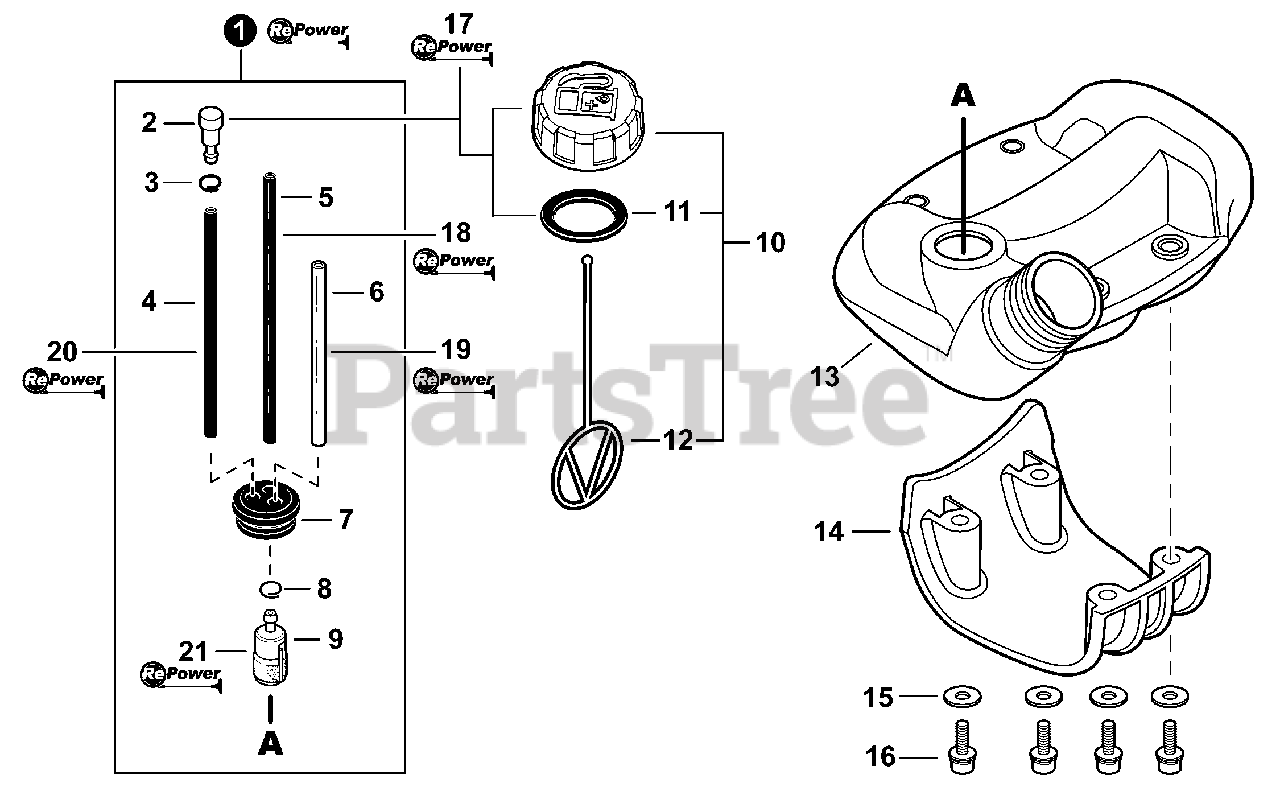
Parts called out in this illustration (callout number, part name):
1	FUEL SYSTEM KIT - REPOWER
2	VENT ASSY
3	CLIP Ø6.5MM
4	PIPE, VENT 3×6×35 BLACK
5	PIPE, FUEL 3×5×195 BLACK
6	PIPE, FUEL 3×6×75 CLEAR
7	GROMMET, FUEL
8	CLIP Ø6
9	FILTER, FUEL 125-528
10	CAP ASSY, FUEL
11	GASKET, FUEL CAP
12	CONNECTOR, CAP L= 100mm
13	TANK, FUEL
14	GUARD, FUEL TANK
15	WASHER 5.5×12×0.8
16	BOLT 5×25
17	CAP/VENT KIT - REPOWER
18	PIPE, FUEL - REPOWER BULK 3×5mm BLACK
19	PIPE, FUEL - REPOWER BULK 3×6mm CLEAR
20	PIPE, FUEL - REPOWER BULK 3×6mm BLACK
21	TUNE-UP KIT - REPOWER
